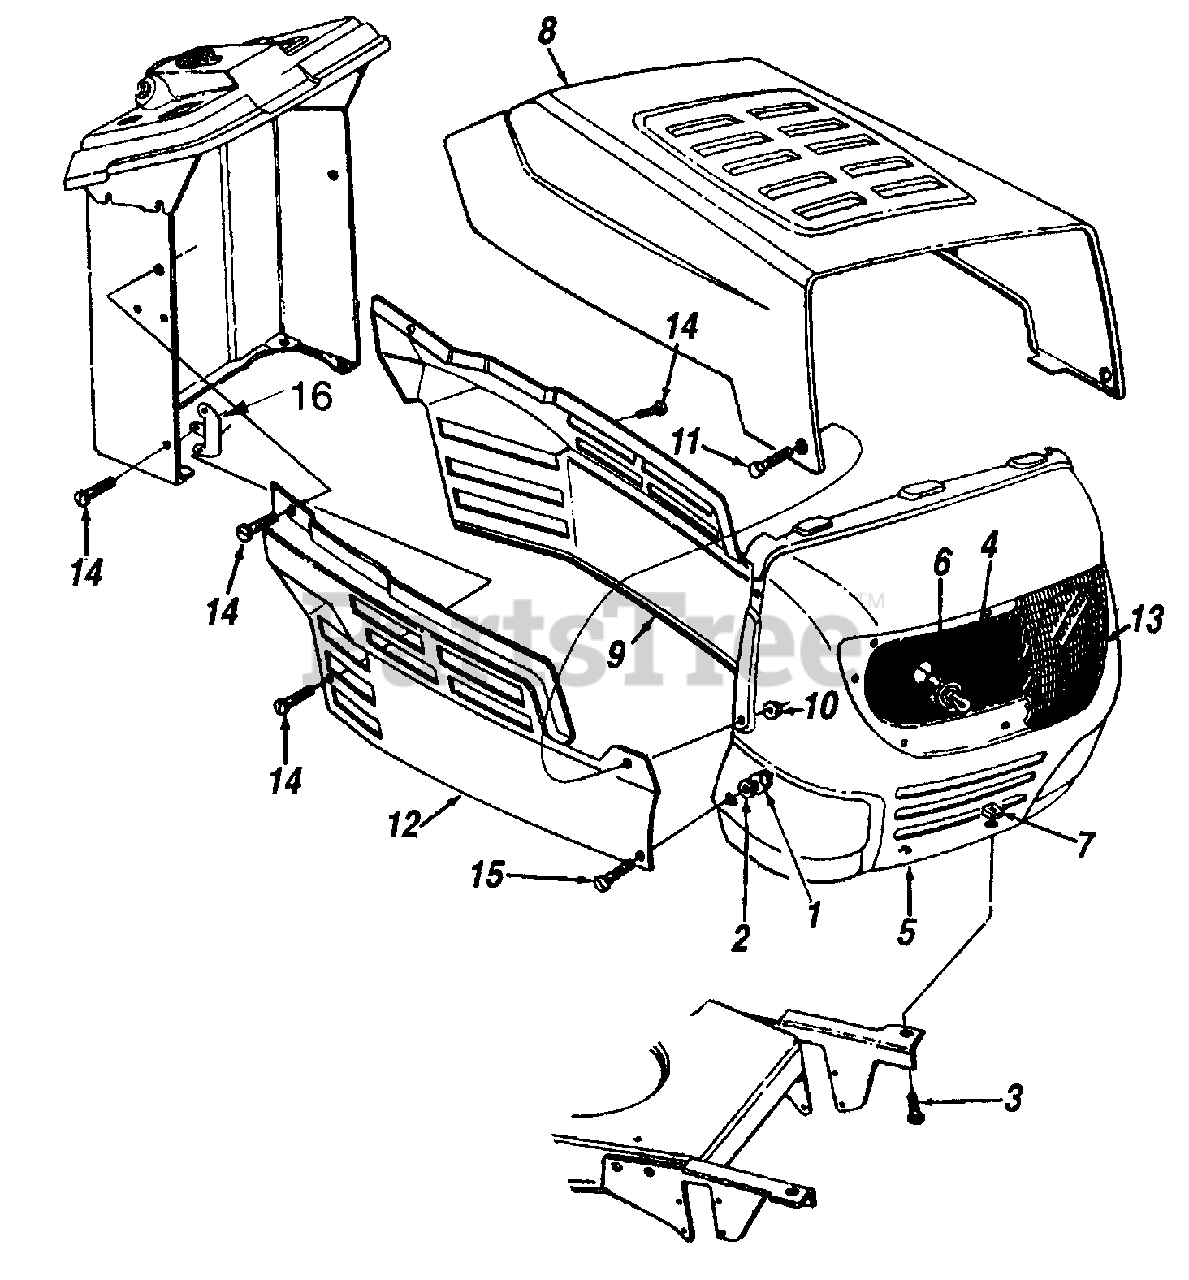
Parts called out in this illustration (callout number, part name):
1	Hex Nut 1/4-20 Thd. (Gr. 5)
2	Bell-Washer 1/4" I.D.
3	Hex Bolt 5/16-18 x .75" Lg.
4	Bulb
6	Socket
7	U-Nut 5/16-18 Thd.
11	Shld. Bolt
14	Hex Tap Scr. 1/4-20 x .5" Lg.
15	Pan Hd. Mach. Scr. 1/4-20 x .5" Lg.
